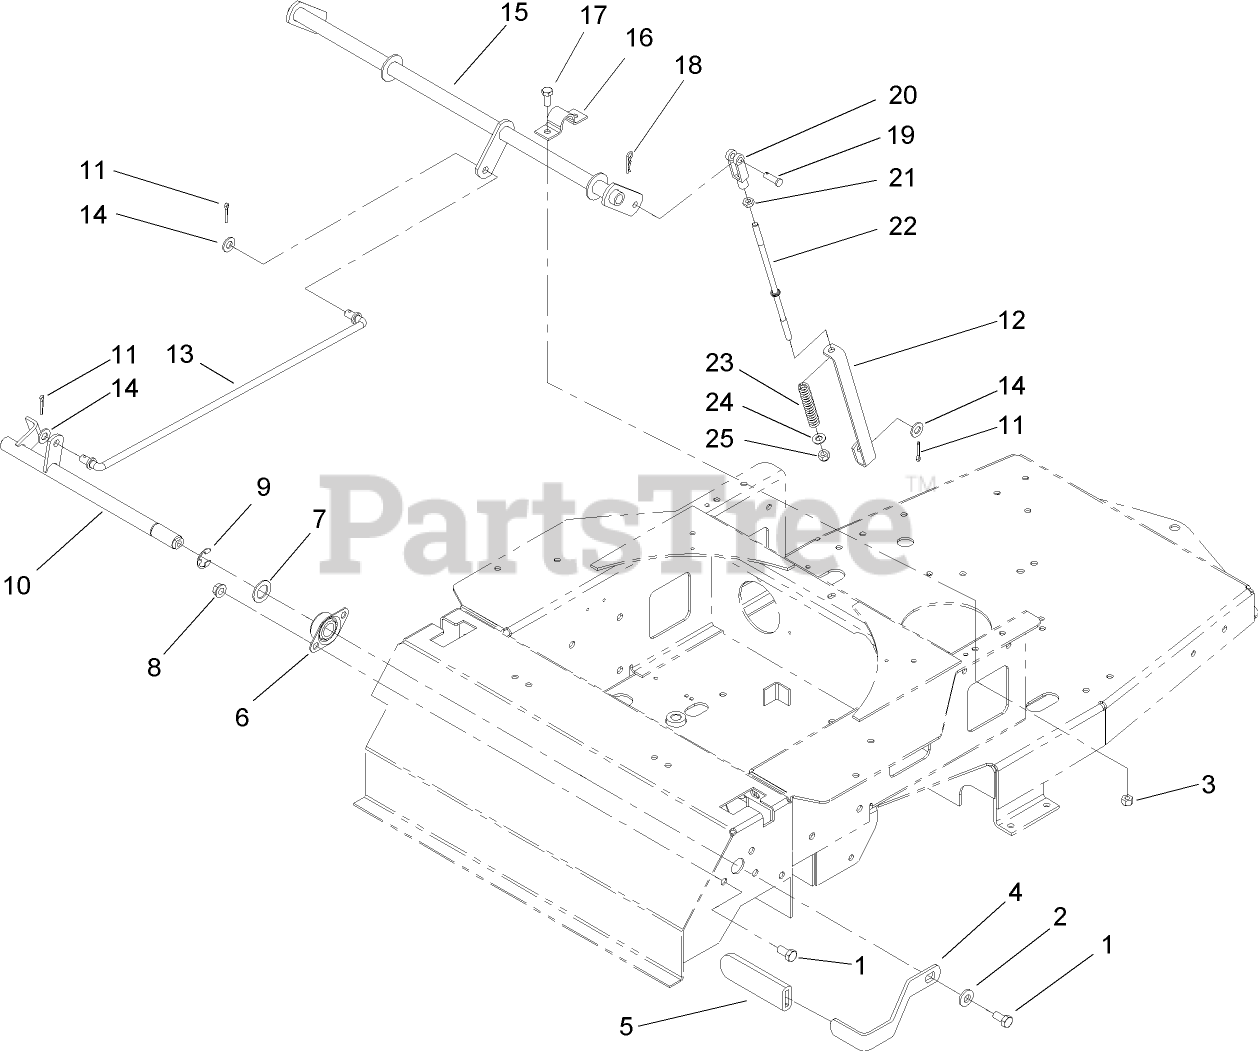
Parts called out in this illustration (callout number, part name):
1	SCREW-HH
2	WASHER-BELLEVILLE
3	NUT-LOCK, NI
4	HANDLE-BRAKE, PARK
5	GRIP-LEVER
6	BEARING-FLANGE, SIDE
7	WASHER
8	NUT-HHF, WHIZ
9	E-RING
10	BRAKE SHAFT ASM
11	PIN-COTTER
12	BRACKET-SPRING, BRAKE
13	ROD-BRAKE, UPPER
14	WASHER-FLAT
15	SHAFT-BRAKE
16	CLAMP-PIVOT, HOC
17	SCREW-HH
18	PIN-COTTER
19	PIN-CLEVIS
20	YOKE-ADJUSTABLE
21	NUT-HEX
22	ROD-BRAKE, UPPER
23	SPRING
24	WASHER-PLAIN
25	NUT-LOCK
